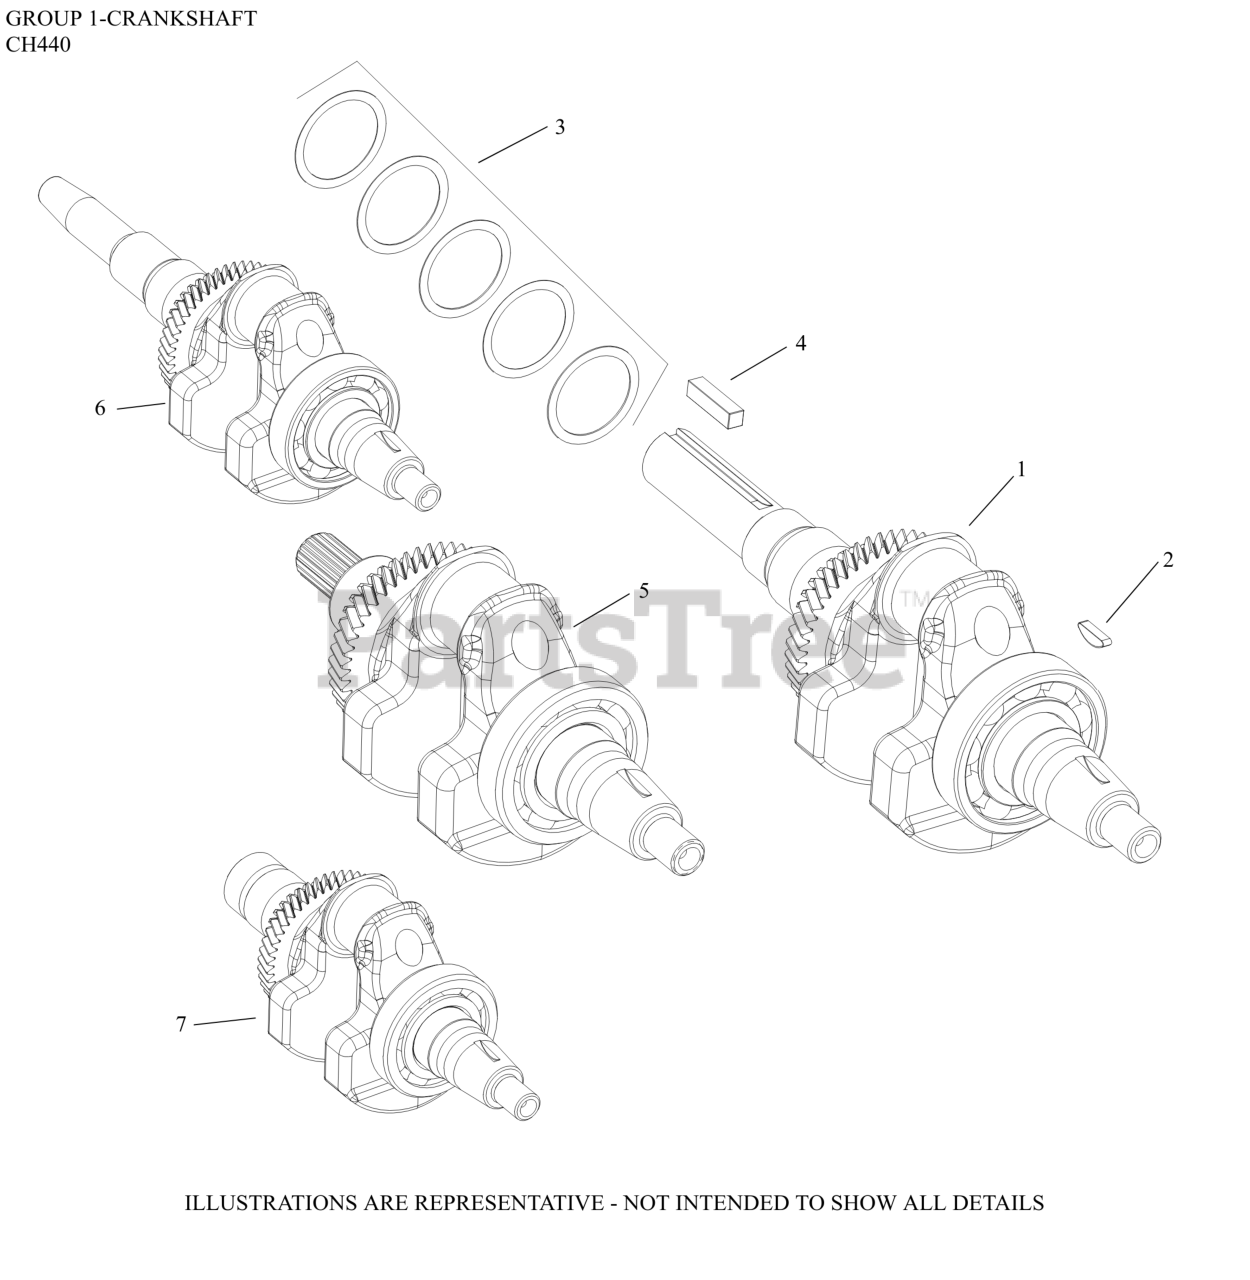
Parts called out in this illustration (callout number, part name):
1	CRANKSHAFT ASSEMBLY
2	KEY, FLYWHEEL
3	KIT, SHIM
4	KEY, SQUARE
